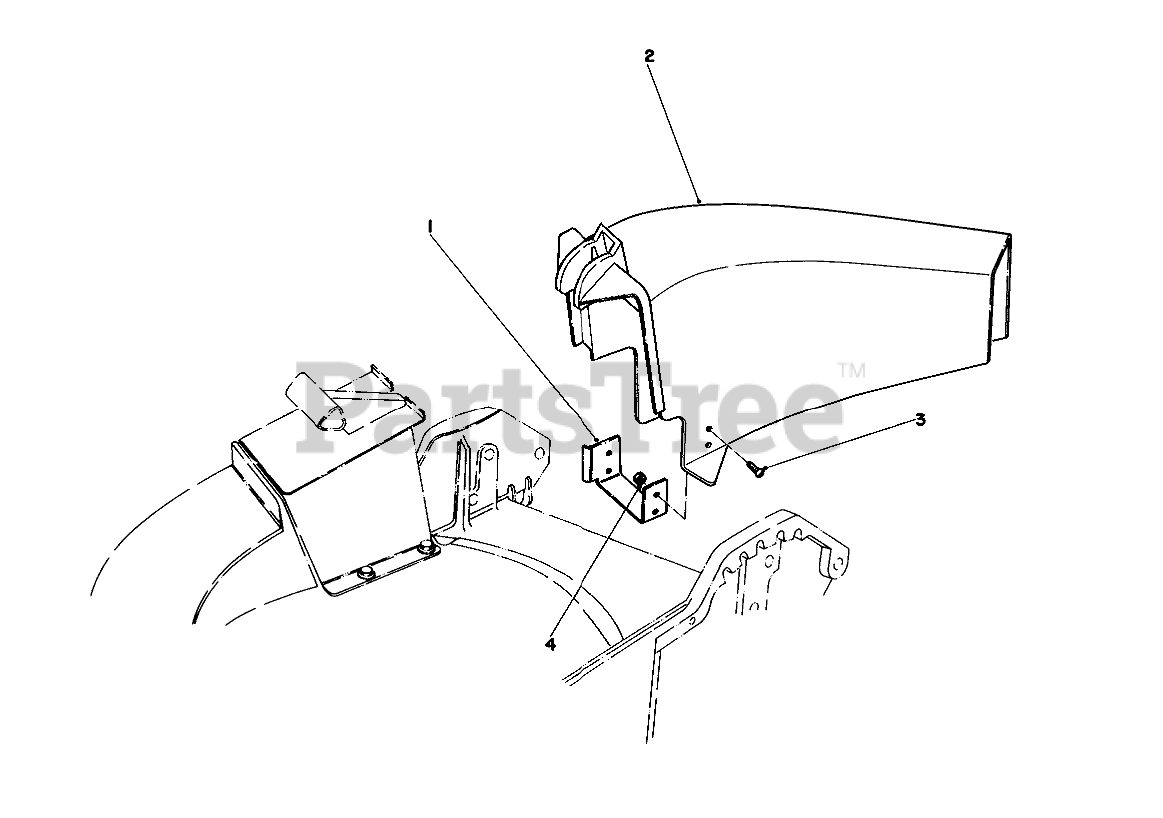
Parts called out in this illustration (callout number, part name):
1	CHUTE BRACKET
2	Chute Discharae
3	6 32 3/8 RD HD MS
4	NUT-HEX
